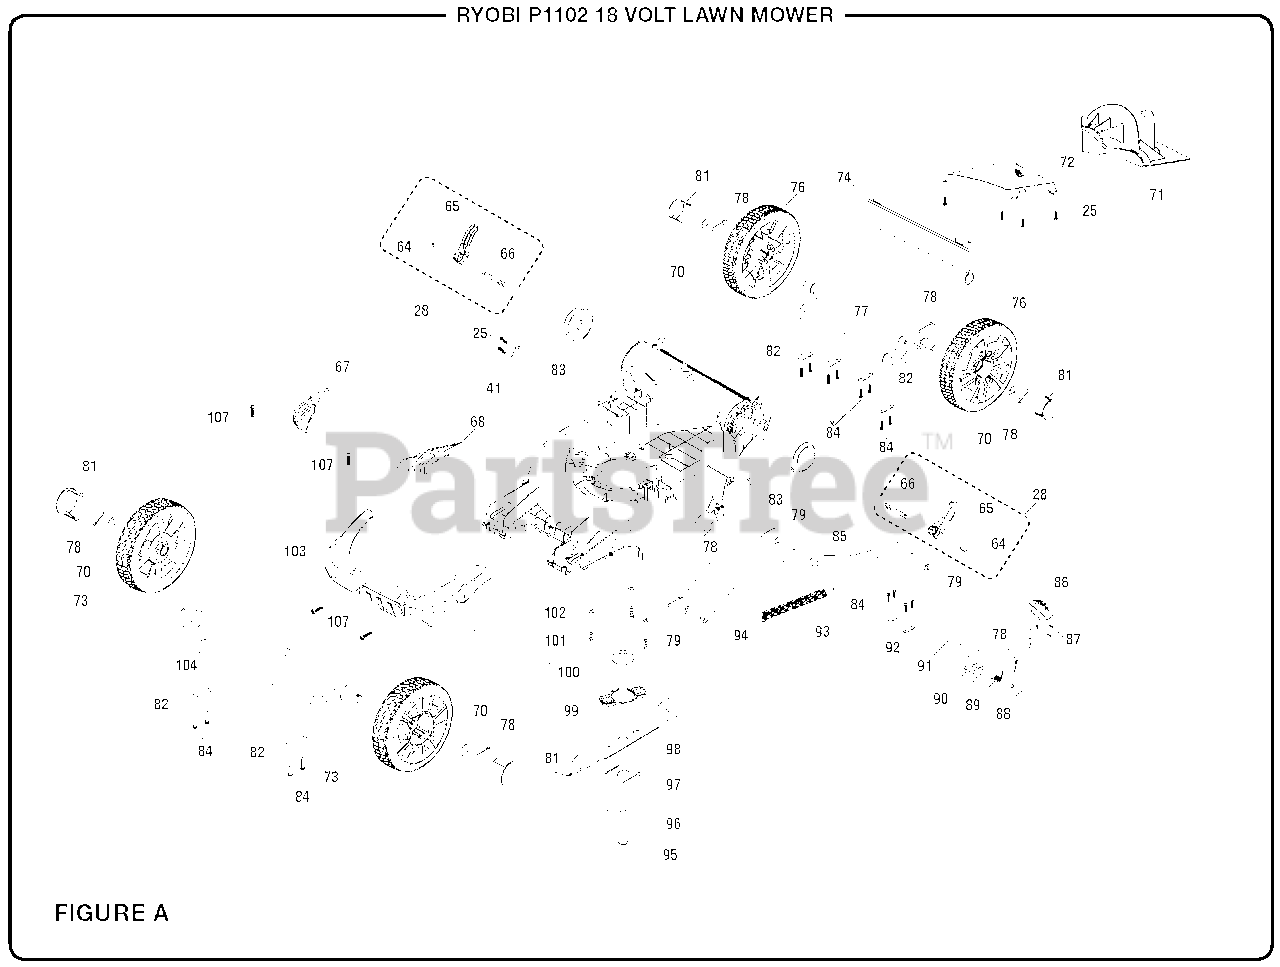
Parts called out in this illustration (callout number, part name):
25	Screw (M4 x 16 mm, T20 Torx Pan Hd.)
28	Handle Lock Assembly
41	Cord Clip
64	Spring Pin
66	Quick Lock Press
67	Grass Protector (Right)
68	Grass Protector (Left)
70	Washer (OD20 x ID13 x 1t)
71	Mulching Plug
72	Rear Cover
73	Front Wheel
74	Rear Skirt
76	Rear Wheel w/Bearing & Cap
77	Rear Wheel Axle
78	Cotter Pin (2.5)
79	Washer (OD18 x ID8.4 x 1t)
81	Wheel Cover
82	Axle Pressure Plate
83	Base (Lock Handle)
84	Screw (M4 x 18 mm, Torx Pan Hd.)
85	Rear Lift Rod
86	Height Adjustment Handle
87	Screw (M3 x 9 mm, Flat Hd.)
88	Height Adjustment Lever
89	Torsion Spring (Height Adjustment)
90	Height Adjustment Bracket
91	Axle (Height Adjustment)
92	Pressure Plate (Height Adjustment)
93	Retention Spring
94	Front Lift Rod
95	Blade Nut (M10)
96	Blade Retainer
99	Blade Holder
100	Motor Shaft Bushing
101	Bolt (M6 x 16 mm, Hex Hd.)
102	Washer (OD15 x ID6 x 1t)
104	Front Wheel Axle
107	Screw (M4 x 20 mm)
